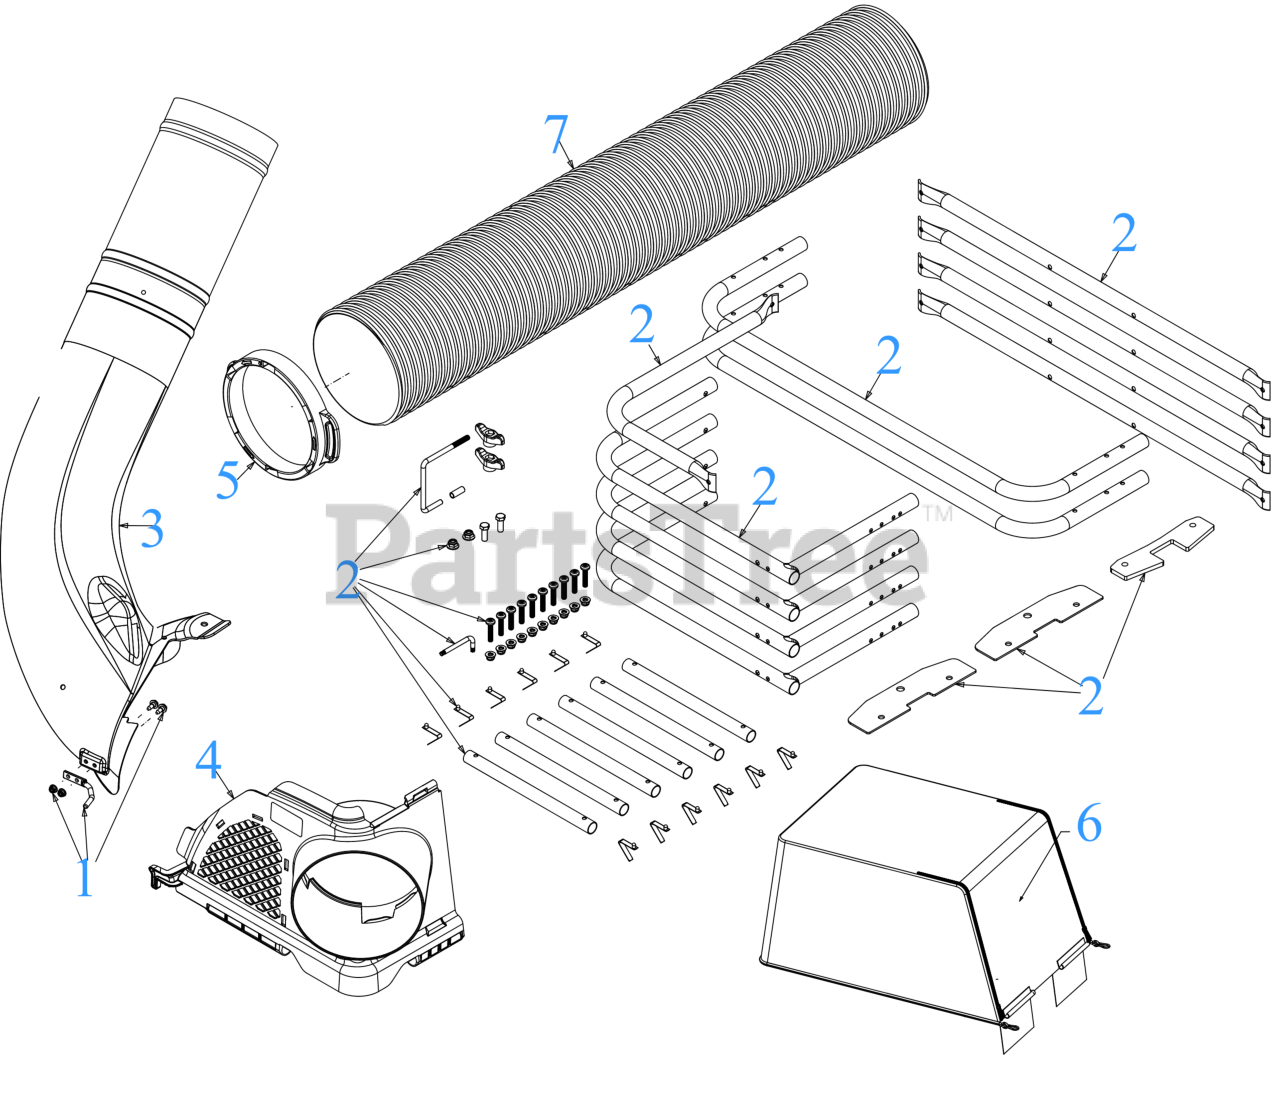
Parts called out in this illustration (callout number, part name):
1	HARDWARE PACK - BAGGER BOOT
2	CART FRAME
3	LOWER BAGGER CHUTE
4	OUTER BAG VENT
5	BAGGER FLEX HOSE RING
6	MESH COVER
7	8" HOSE (58"LG)
